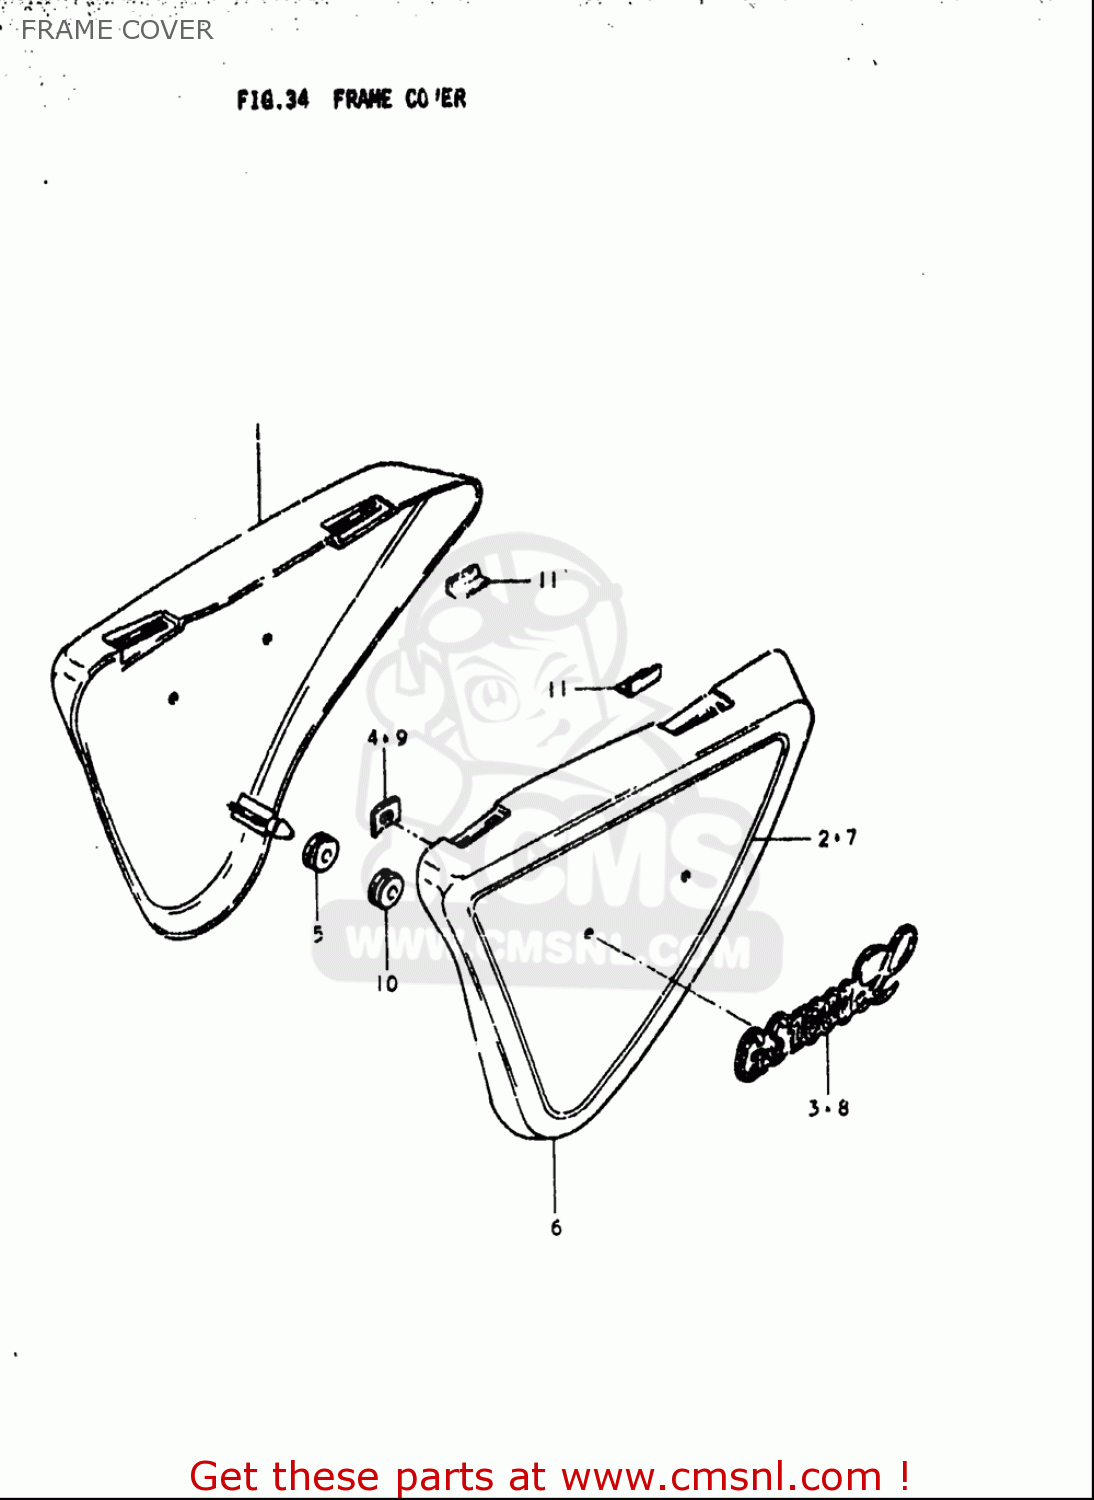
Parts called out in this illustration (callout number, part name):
1	COVER SET,FRAME,R
3	EMBLEM,FRAME COVER
4	NUT
5	CUSHION
6	COVER,FRAME,L
7	TAPE SET
8	EMBLEM,FRAME COVER
9	NUT
10	CUSHION
11	CUSHION,FRAME COVER
